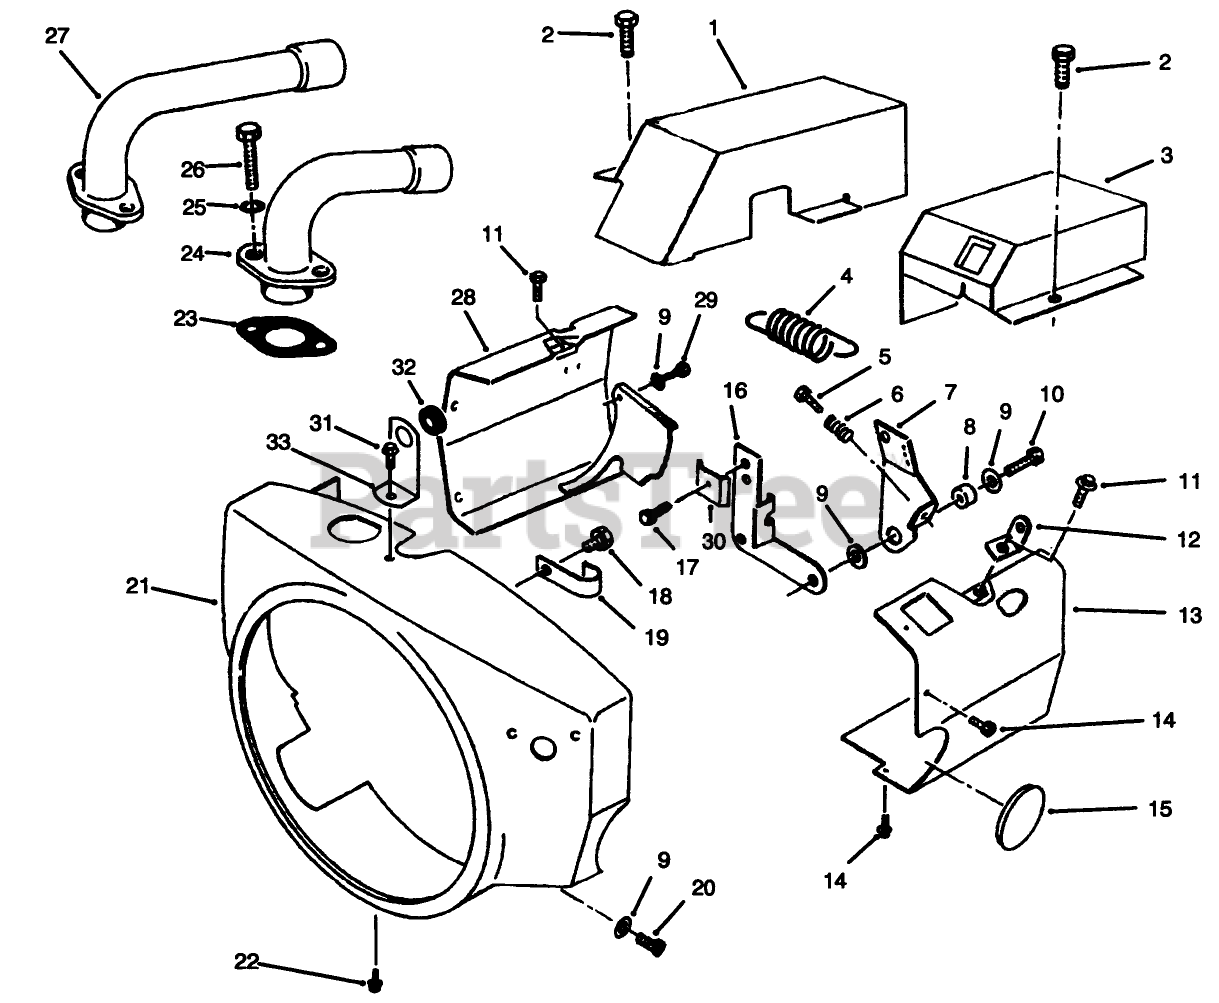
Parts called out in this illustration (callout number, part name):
1	LH EXHAUST TUBE COVERR
2	HX WSHR HD CAPSCREW
3	RH EXHAUST TUBE COVERR
4	SPRING
5	SCREW-TAP
6	SPRING
8	BUSHING
9	WASHER-FLAT
10	SCREW-HWH
11	SCREW-HHF
12	Bracket-Lift
13	CYL AIR HOUSING ASSY
14	SCREW-HWH
15	AIR SEAL GROMMET
16	BRACKET-GOVERNOR
17	SCREW-TAPPING
18	SCREW-HHF
19	CLIP-WIRE
20	SCREW-HH
21	Housing-Blower
22	HEX HD CAPSCREW
23	GASKET
24	EXHAUST TUBE
25	WASHER-FLAT
26	SCREW-HH
27	EXHAUST TUBE
28	Housing-L.H.
29	SCREW-HH
31	SCREW-HWHTF
32	GROMMET
33	FUEL LINE BRACKET
